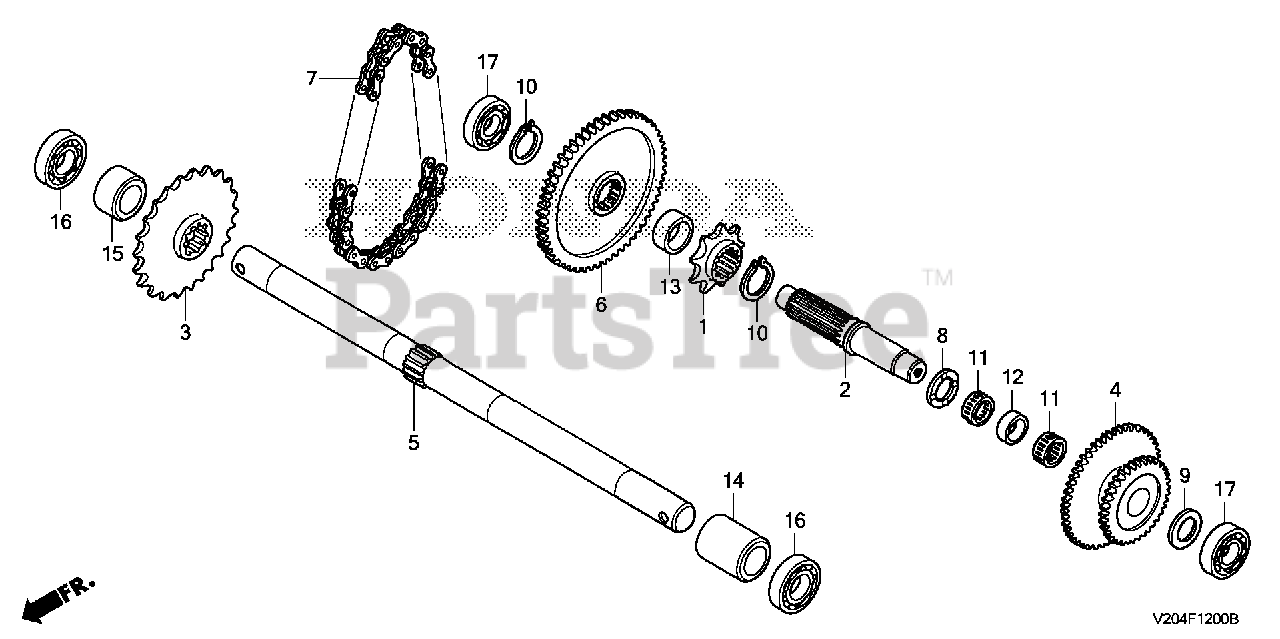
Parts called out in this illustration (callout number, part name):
1	SPROCKET, DRIVE (9T)
2	SHAFT, FINAL
3	SPROCKET, DRIVEN (23T)
4	GEAR, FINAL (35T/53T)
5	SHAFT, WHEEL
6	GEAR, FINAL DRIVEN (59T)
7	CHAIN, FINAL (DID520HK-32L)
8	WASHER, THRUST (20MM)
9	WASHER, THRUST (17MM)
10	CIRCLIP (OUTER) (22MM) (NOT AVAILABLE)
11	BEARING, NEEDLE (20X24X13)
12	COLLAR, FINAL GEAR
13	COLLAR, SPROCKET
14	COLLAR, WHEEL SHAFT (A)
15	COLLAR, WHEEL SHAFT (B)
16	BEARING, RADIAL BALL (6205)
17	BEARING, RADIAL BALL (6303) (NOT AVAILABLE)
